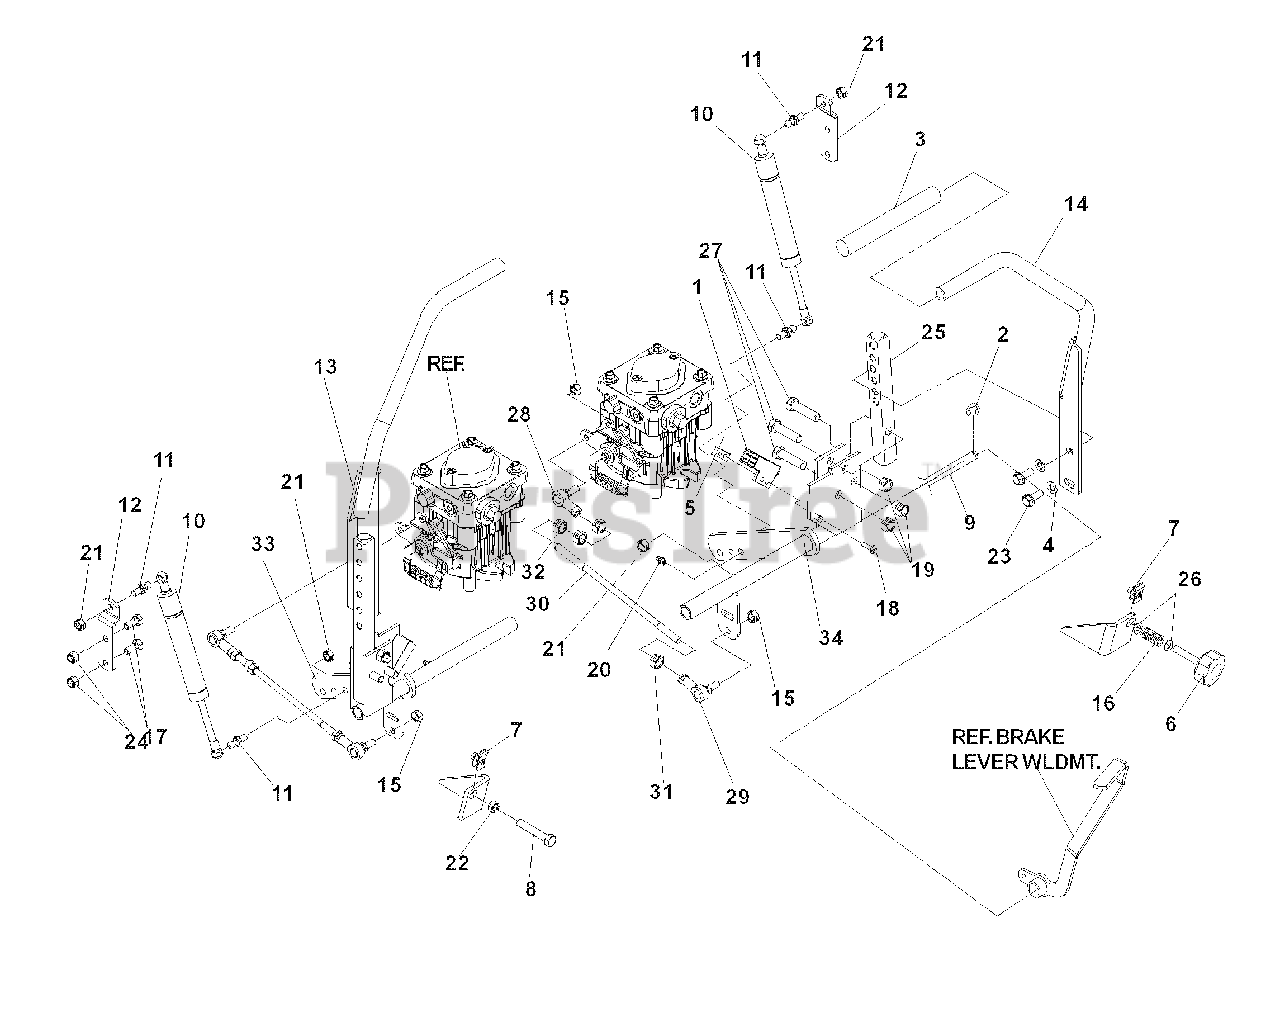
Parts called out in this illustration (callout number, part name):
1	SWITCH, INTERLOCK
2	E-RING, 1/2
3	CUSHION, DRIVE LEVER
4	WASHER, 3/8, SPRING, SPEC
5	NUT, #10-24
6	ADJUSTMENT KNOB
7	NUT, 5/16-18, U-TYPE
8	HCS, 5/16-18 x 1 3/4, TPBLT
9	CONTROL SHAFT
10	DAMPENER
12	DAMPENER ARM
13	DRIVE LEVER, RIGHT
14	DRIVE LEVER, LEFT
15	NUT, 5/16, NYLOC
16	COMPRESSION SPRING
17	HCS, 5/16-18 x 3/4
18	SCREW, #10-24 x 5/8,COMBO
19	NUT, 3/8-16, NYLOC
20	ZERK, STRAIGHT, 1/4-28
21	NUT, 5/16 -18, CENTERLOCK
22	NUT, 5/16 -18
23	HCS, 3/8 -16 x 1
24	NUT, 5/16 -18, NYLOC
25	ARM CONTROL SHAFT
26	WASHER, 5/16
27	HCS, 3/8 -16 x 1 3/4
28	ROD END, SPHERICAL, RT
29	ROD END, SPHERICAL, LT
31	NUT, 5/16, JAM, LH
33	DRIVE CONTROL, RIGHT
34	DRIVE CONTROL, LEFT
